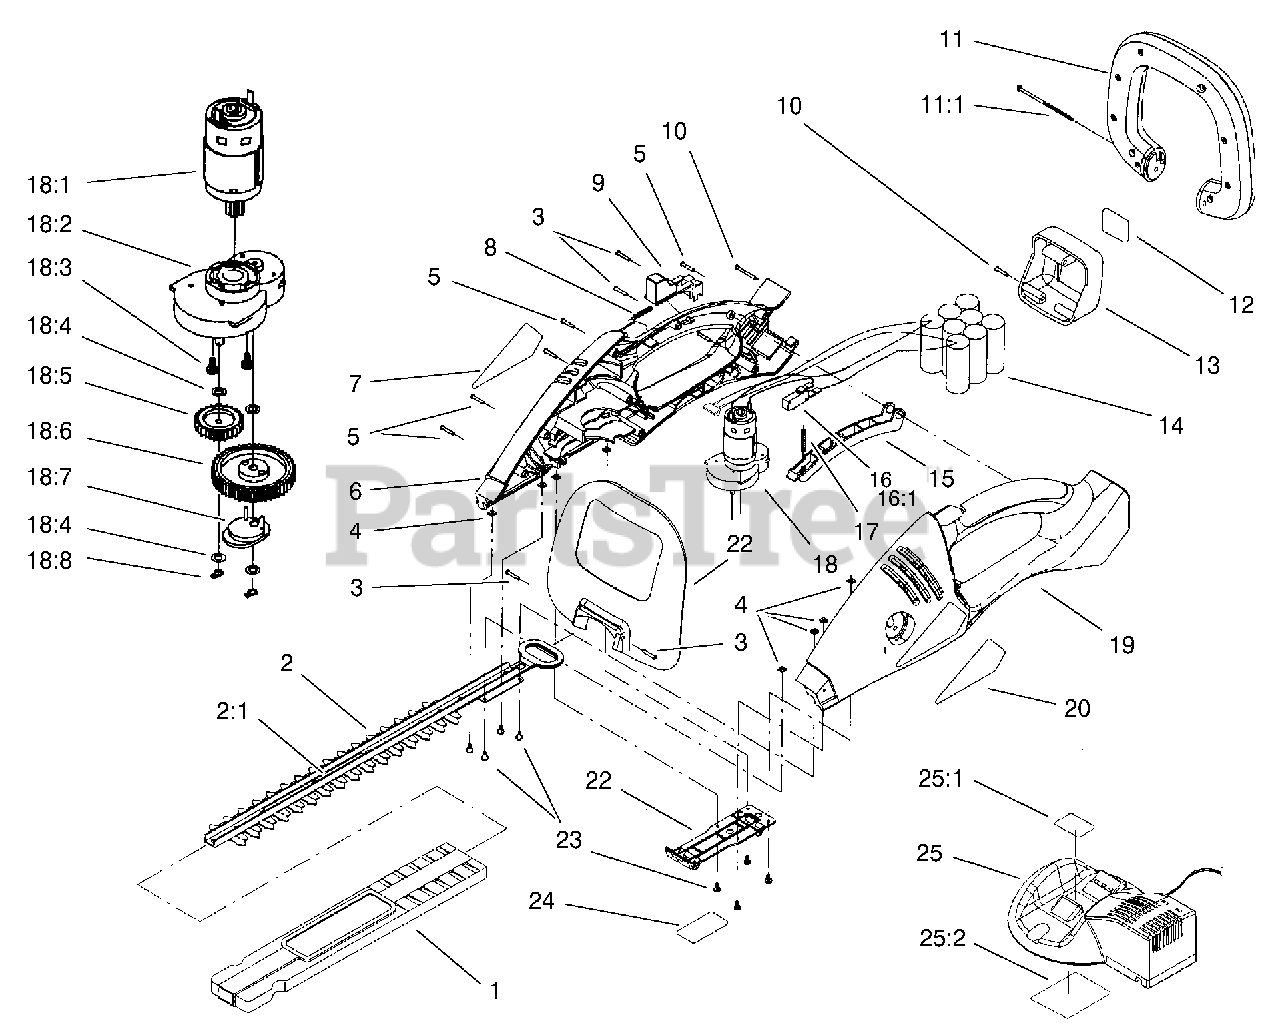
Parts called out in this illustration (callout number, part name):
1	PROTECTOR - BLADE, 18"
2	BLADE ASM
2:1	DECAL - SAFETY, BLADE
3	Screw-PPH
4	NUT - SQUARE
5	SCREW - PPH
6	Housing-Cover
7	Decal-Housing, Cover
8	SPRING - BUTTON, SAFETY
9	BUTTON - SAFETY
10	SCREW - PPH
11	SAFETY HANDLE ASM
11:1	SCREW - PPH
12	DECAL - COVER, BATTERY
13	Cover-Battery
14	BATTERY ASM
15	BUTTON - ON/OFF
16	HARNESS - WIRE ASM
16:1	Switch-On/Off
17	SPRING - BUTTON, ON/OFF
18	MOTOR AND GEAR TRAIN ASM
18:1	MOTOR ASM
18:2	HOUSING - GEAR ASM
18:3	SCREW - PPH
18:4	WASHER - FLAT
18:5	Gear-Center
18:6	GEAR - FINAL
18:8	RING - RETAINING, EXTERNAL
19	Housing-Support
20	Decal-Housing, Support
21	GUARD - HAND
22	COVER - BOTTOM
23	SCREW - PPH
24	Decal-Model/Warning
25	CHARGER ASM
25:1	Decal-Warning
25:2	Decal-Nameplate, Charger
